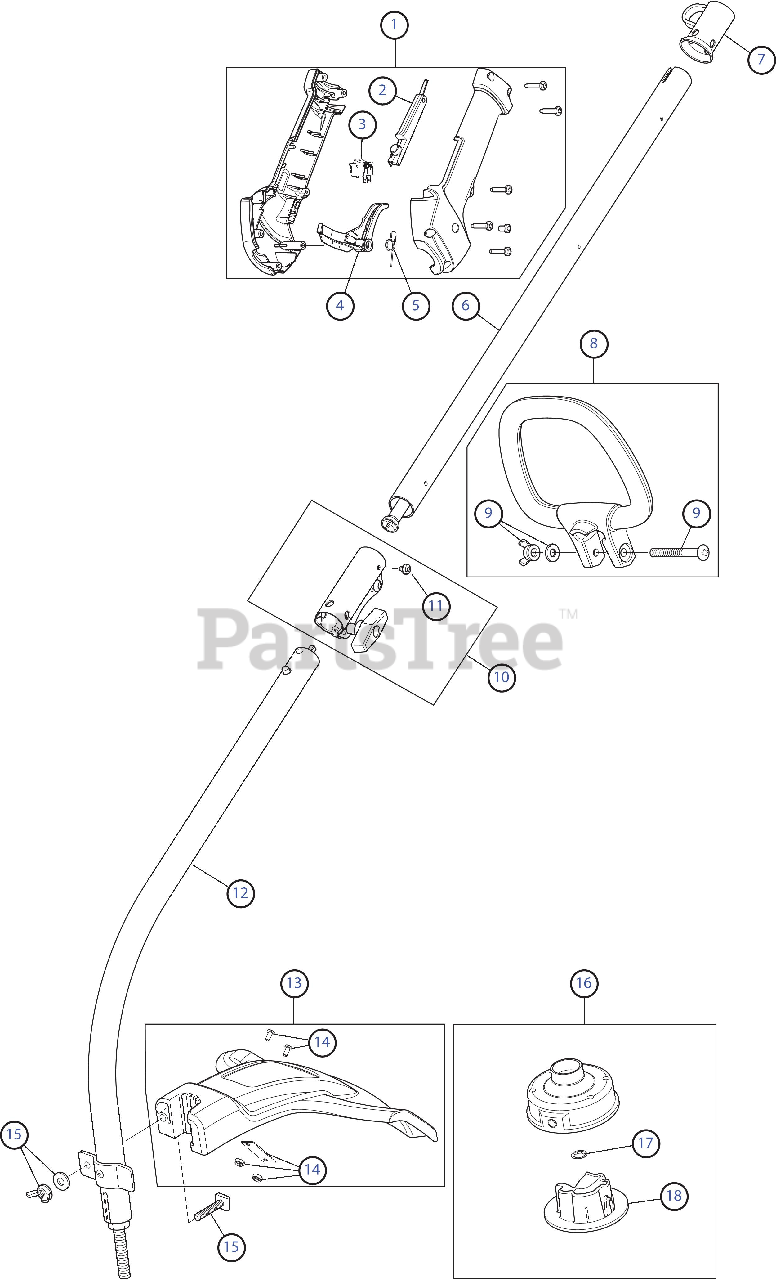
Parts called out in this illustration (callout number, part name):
1	Throttle Housing Assembly (Incl. 2 - 5)
2	Throttle Trigger Lock-Out
3	Trigger Switch Assembly
4	Throttle Trigger Spring
5	Throttle Trigger
6	Upper Shaft Housing Assembly
7	Hanger
8	D-Handle (Incl. 9)
9	D-Handle Hardware Assembly
10	Split Boom Coupler (Incl. 11)
11	Anti-Rotation Screw
12	Lower Shaft Housing Assembly
13	Shield Assembly (Incl. 14)
14	Blade Assembly
15	Shield Mounting Hardware
16	Fixed String Head Assembly (Incl. 17 & 18)
17	Retainer
18	Fixed String Cap
